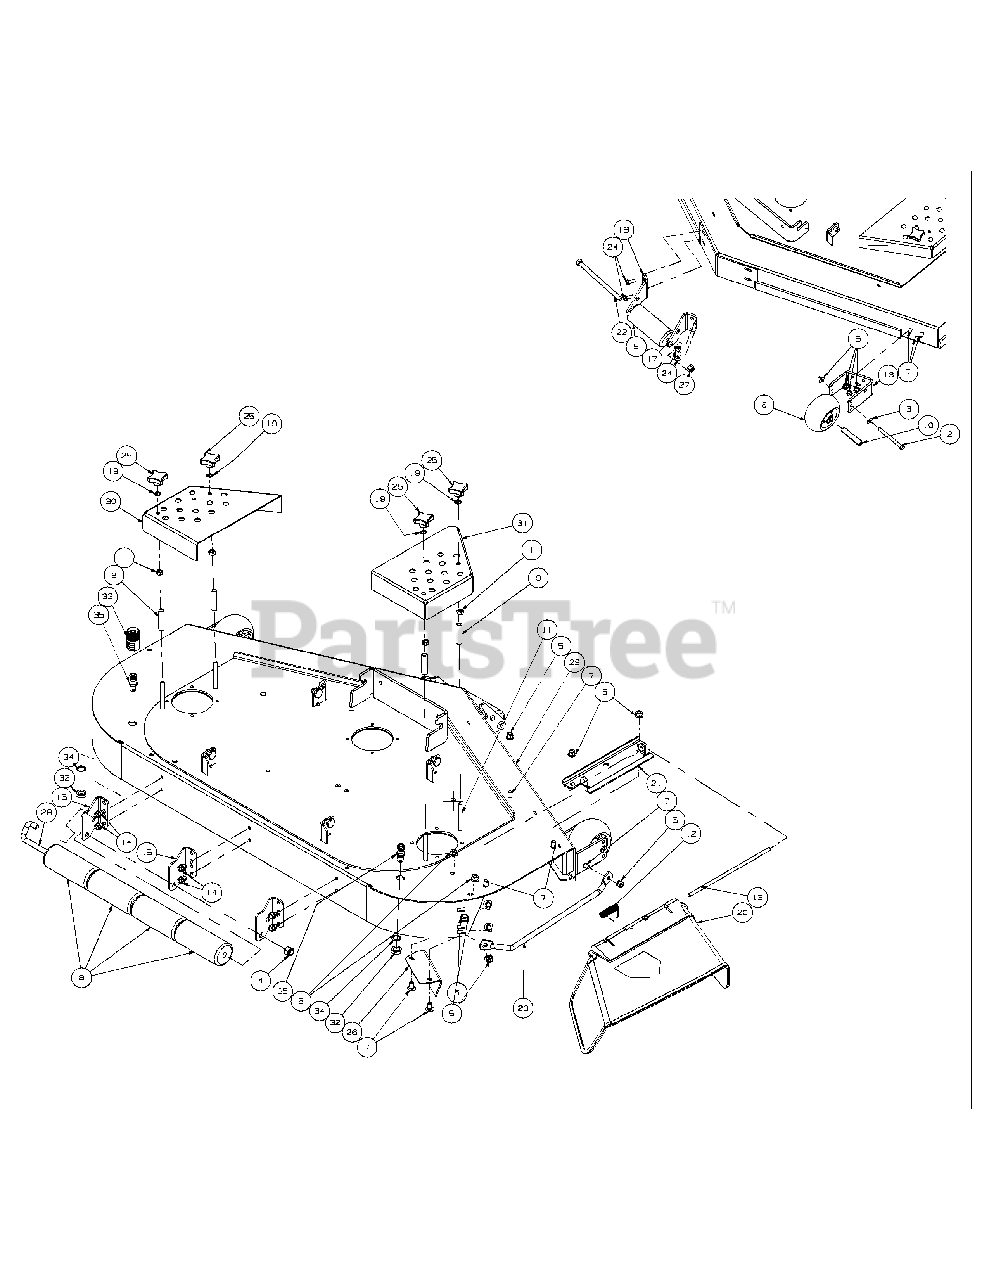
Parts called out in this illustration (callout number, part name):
1	Nut, 3/8-16, Hex
2	Hex Cap Screw, 3/8-16, 3.75
4	Hex Nut, 1/2-13, Insert Lock
5	Hex Nut, 3/8-16 Flange Lock
6	Complete Wheel, 5.00 Dia
7	Carriage Bolt 3/8-16 x .75
8	Front Roller
10	Wheel Spacer
11	Carriage Bolt, 3/8-16 x 3.50
12	Torsion Spring
13	Chute Deflector Rod
14	Self Tapping Screw, 5/16-18 x 1/2
19	External Washer, 3/8
20	Deflector Chute
21	Deflector Chute Bracket
22	Hex Cap Screw, 1/2-20 x 7.50
23	Fabricated Deck Finger Guard
24	Self Tapping Screw, 3/8-16 x 0.875
25	Plastic Knob
26	Fabricated Deck, Chute Bracket
27	Lock Nut, Nylon Insert, 1/2-20
28	J-Hook w/ Threaded Roller
29	54 Fabricated Deck Assembly
32	Hex Nut, M16-1.5
33	Water Nozzle Adaptor
34	Lock Washer, 17 x 23.8 x 1.95
35	Deck Water Nozzle
